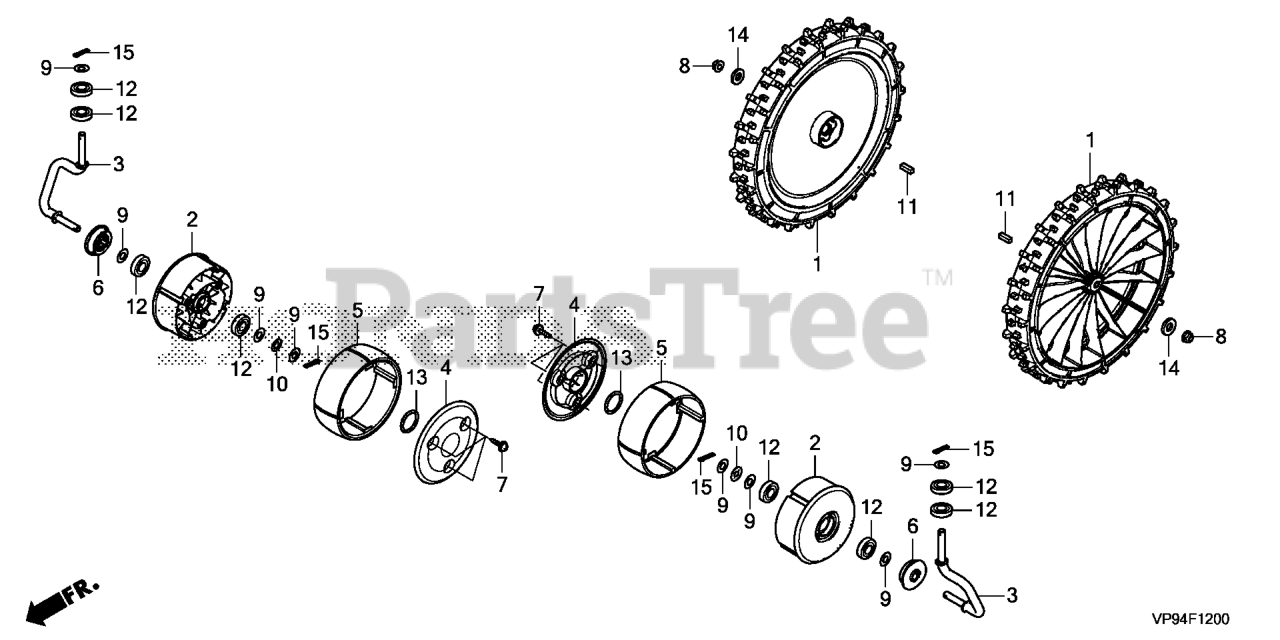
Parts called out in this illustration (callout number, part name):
1	WHEEL, RR.
2	CASTER, FR.
3	ROD, FR. CASTER
4	COVER, CASTER
5	TIRE, CASTER
6	CAP, FR. WHEEL
7	SCREW, TAPPING (5X16)
8	NUT, SELF-LOCK (6MM)
9	WASHER, THRUST (7.2X14X1)
10	WASHER, WAVE (7MM)
11	KEY FLAT (4X4X14)
12	BEARING (7X17X5)
13	O-RING, FR. CASTER
14	WASHER, PLAIN (6MM)
15	PIN, COTTER (1.6X12)
